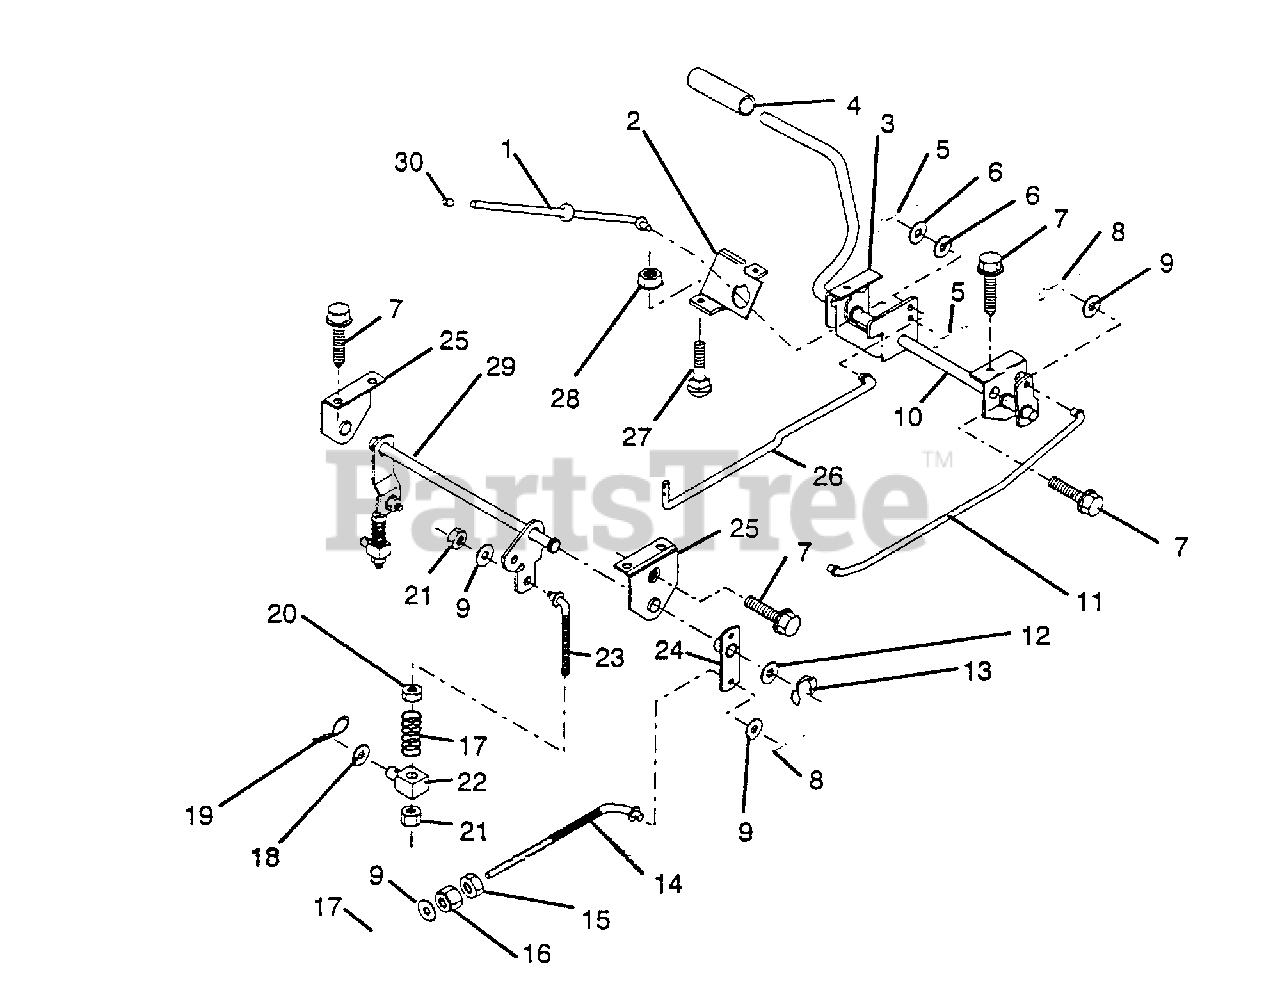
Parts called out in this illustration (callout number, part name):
1	Rod, Parking Brake
2	Bracket, Parking Brake
3	Bracket, L.H. Clutch Pedal
4	Cover, Pedal
5	Pin, Cotter
6	Washer, 13/32 x 5/8 x 16 Ga.
7	Screw Hex Thdrol 5/16-18 x 1/2
8	Pin, Cotter
9	Washer 13/32 x 13/16 x 16 Ga.
10	Assembly, Clutch/Brake-Pedal
11	Rod, Front Brake
12	Washer 25/32 x 1-1/8 x 16 Ga.
13	Ring, Clip
14	Rod, Rear Brake
15	Nut, Hex Jam 3/8-16 UNC
16	Nut, Lock, Hex with Wsh Insert 3/8-16 UNC
17	Spring, Brake Rod
18	Washer 13/32 x 1-1/4 x 12 Ga.
19	Spring, Retainer
20	Nut, Centerlock 3/8-16 UNC
21	Nut, Crownlock 3/8-16 UNC
22	Trunnion, Lift
23	Link, Threaded
24	Assembly, Brake Pivot Arm
25	Bracket, Lift Shaft
26	Rod, Clutch
27	Bolt, Carriage 5/16-18 UNC x 3/4
28	Nut, Keps 5/16-18 UNC
29	Assembly, Rear Mower Lift
30	Cap, Plunger
